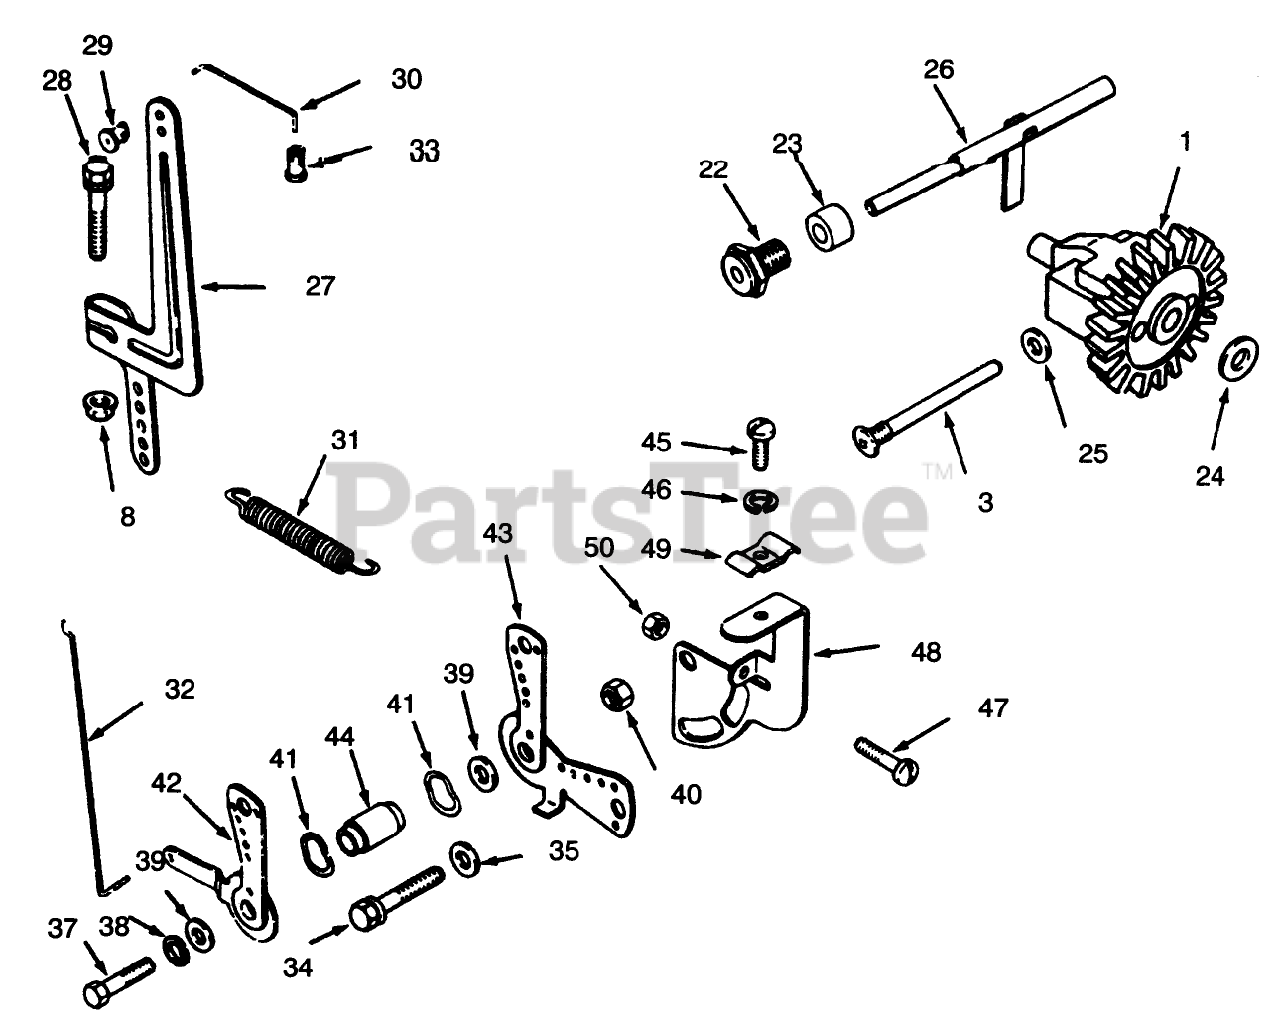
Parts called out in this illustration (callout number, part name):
1	KOHLER A-235743-5
3	KOHLER 231355
8	KOHLER X-799-1
22	KOHLER 235476
23	KOHLER X-400-80
24	KOHLER 237022
25	KOHLER 25-468-01
26	VNDR #A-235256-S
27	KOHLER 47-090-20
28	KOHLER X-776-1
30	KOHLER 47-079-10
31	KOHLER 47-091-01
32	KOHLER 47-079-01
34	KOHLER X-132-6
35	KOHLER X-25-72
37	KOHLER X-5-26
38	KOHLER X-20-1
39	KOHLER X-25-63
40	KOHLER X-76-2
41	KOHLER 275690
42	KOHLER 47-090-07
43	KOHLER 47-090-08
44	KOHLER 47-112-02
45	KOHLER X-67-51
46	KOHLER 25-468-04
47	KOHLER 232556
48	KOHLER 47-126-09
49	KOHLER 47-237-02
50	KOHLER X-72-4
